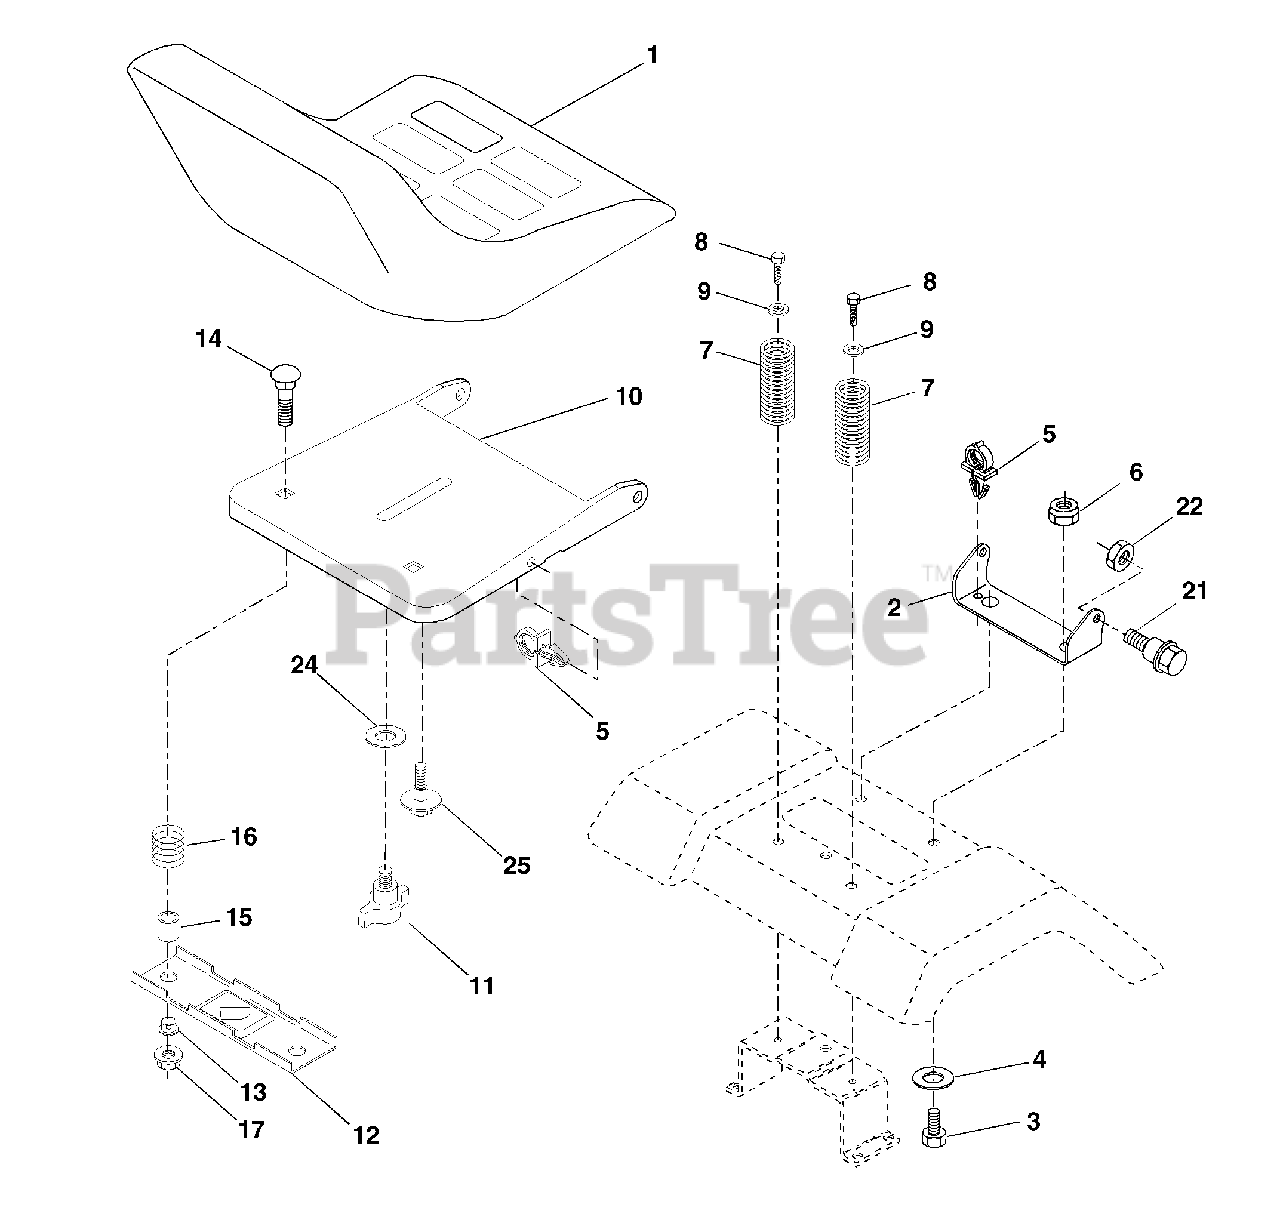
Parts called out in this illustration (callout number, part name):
1	Seat
2	Bracket Pivot Seat 8 720
3	Bolt Fin Hex 3/8-16unc X 1
4	Washer 13/32 X 1 X 10 Ga
5	Clip Push-In
6	Nut Hex w/Ins. 3/8-16 Unc
7	Spring Seat Cprsn 2 250 Blk Zi
8	Screw 3/8-16 X 1
9	Washer 13/32 X 1 X 14 Ga.
10	Pan Seat
11	Knob Seat Adj Wingnut
12	Bracket Mounting Switch
13	Bushing Snap Blk Nyl 50 Id
14	Bolt Rdhd Sqnk 1/4-20x1-1/2
15	Spacer Split 28x 96 Yel Zinc
16	Spring Cprsn 1 27 Blk Pnt
17	Nut Lock 1/4 Lge Flg Gr 5 Zinc
21	Bolt Shoulder 5/16-18 Unc
22	Nut Hex Lock W/Ins 5/16-18
24	Washer 17/32 X 1-3/16 X 12 Ga.
25	Bolt Shoulder 5/16-18 X 62
